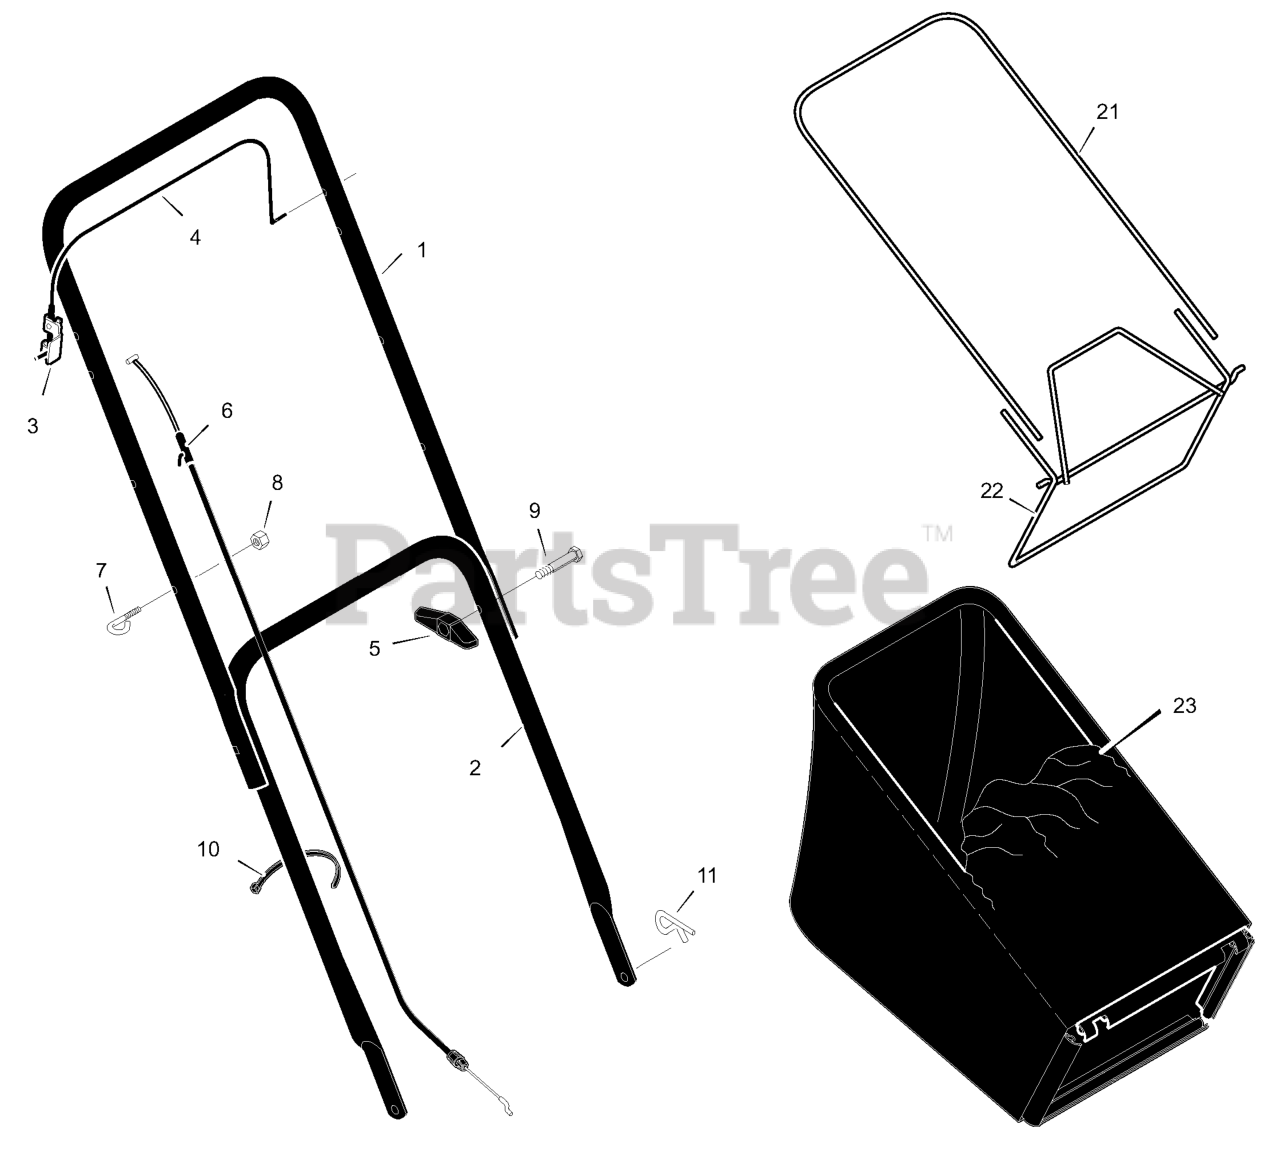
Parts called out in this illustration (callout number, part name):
1	Handle, Upper
2	Handle, Lower
4	Knob, Plastic
7	Locknut
12	Guide, Rope
13	Engine Stop Lever
14	Bracket, Stop Lever
15	Fastener, Cable
16	Engine Stop Cable
17	Hair Pin
21	Frame, Top
22	Frame Assembly
23	Bag, Cloth
